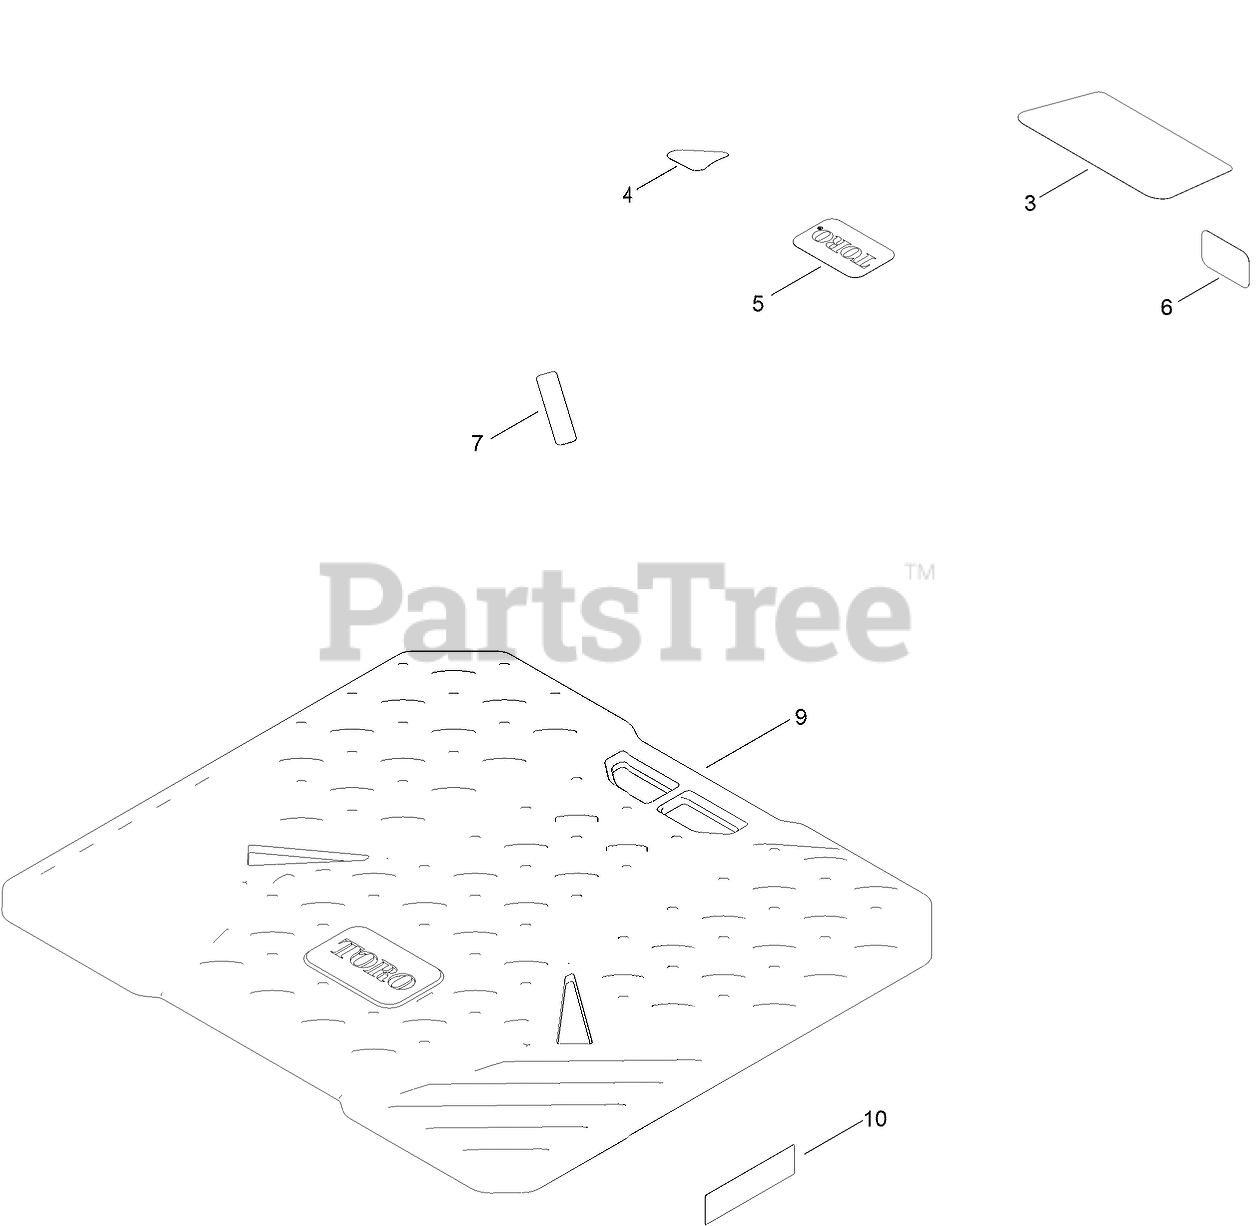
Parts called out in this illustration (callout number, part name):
3	DECAL-ENGINE
4	DECAL-DRAIN, OIL
6	PLACARD-INTAKE
7	DECAL-SHUTDOWN
9	FLOOR MAT
